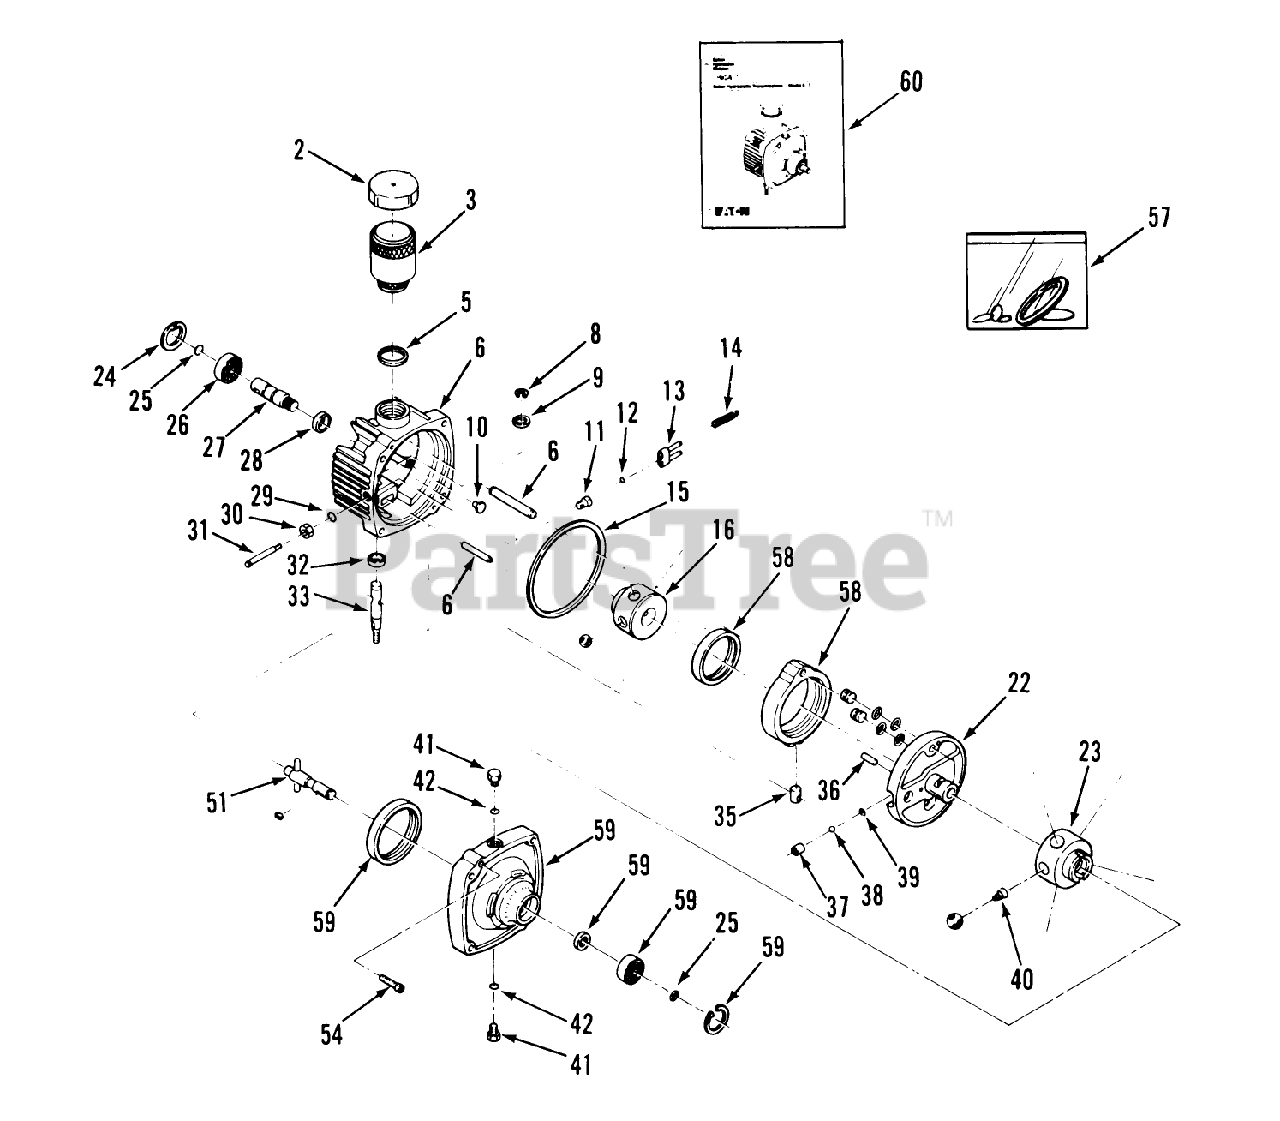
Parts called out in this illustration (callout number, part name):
2	RESERVOIR COVER
3	BODY-RESERVOIR
5	SEAL-RING SQUARE CUT
14	SPRING-VALVE
16	SUB-ASS'Y PUMP ROTOR
25	SNAP-RING
26	BEARING-BALL (INPUT)
27	SHAFT-INPUT
32	SEAL-OIL
57	KIT-OVERHAUL SEALING
59	SUB-ASS'Y BODY
60	Hydrostatic Transmission Repair Manual
